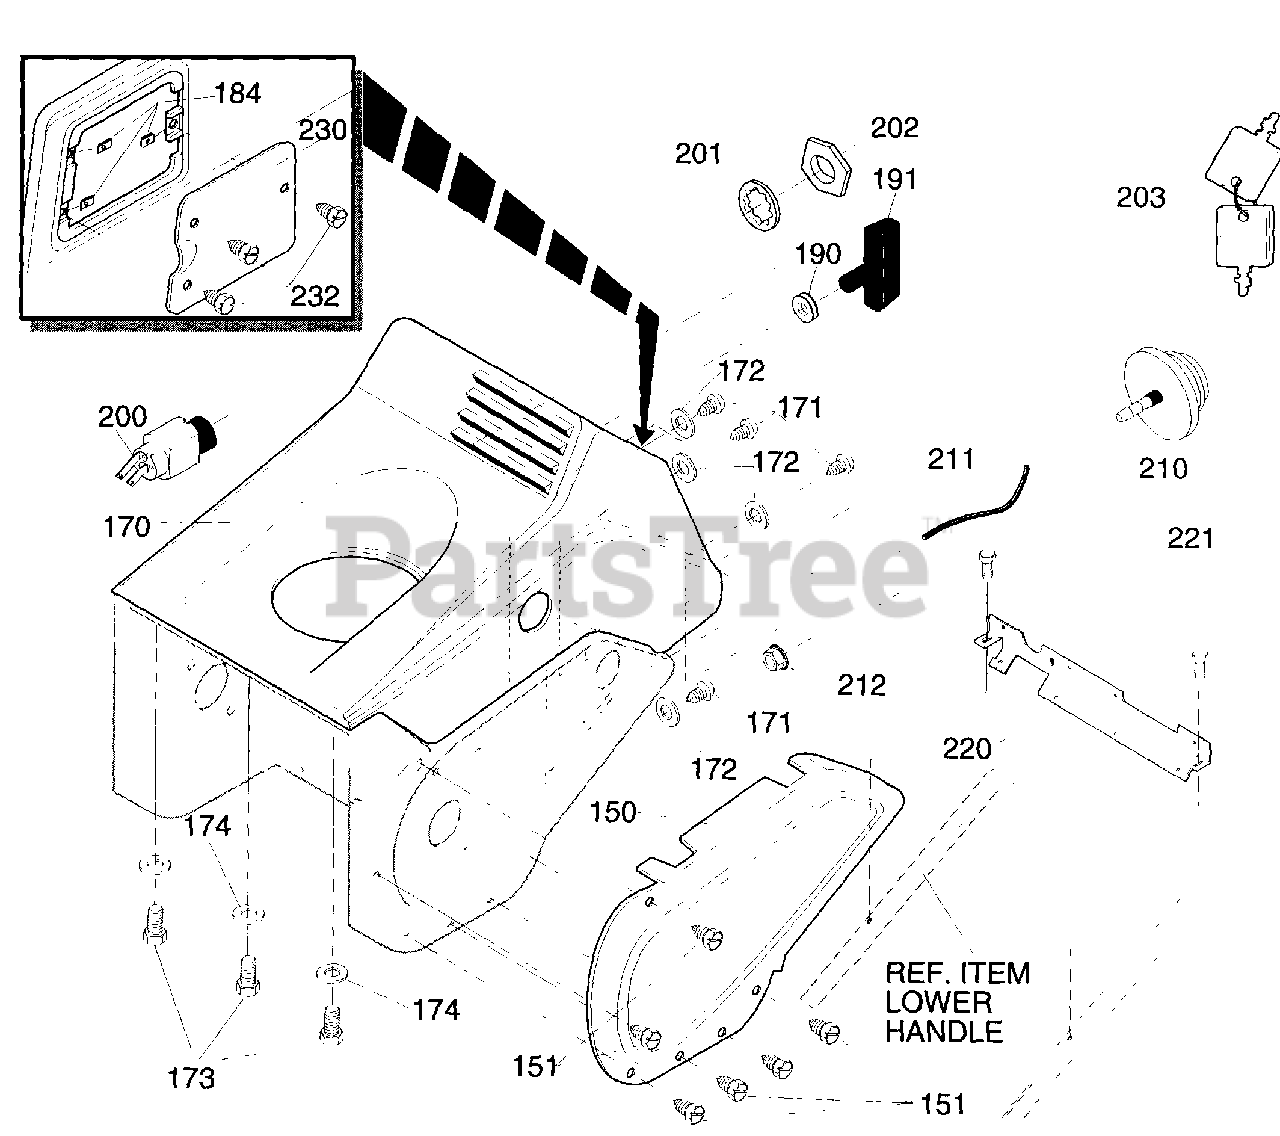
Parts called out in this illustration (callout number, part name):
150	COVER, BELT
151	SCREW, 10-24 X .38 SLHWATAP
170	COVER, TOP
171	SCREW, #10-24 X .63 TRPHTAP
172	WASHER, FLAT
173	SCREW, #10-14 X .63
174	WASHER, FLAT
184	NUT, TINN "U"
190	GROMMET & WASHER, ROPE GUIDE
191	KNOB, PLASTIC
200	SWITCH, IGNITION
201	WASHER, REGINTLK
202	NUT, 5/8-32 HXHD IGN SWIT
203	2 KEYS & RING, ASSY
210	PRIMER, ENGINE 2CY
211	HOSE, PRIM 5.75 LG
212	NUT, 1/4-20 HEXKEPS
220	BRACKET, SHROUD MNTG
221	SCREW, #10-24 X .63 TRPHTAP
230	DOOR, ACCESS
232	SCREW #10-16 X .75
